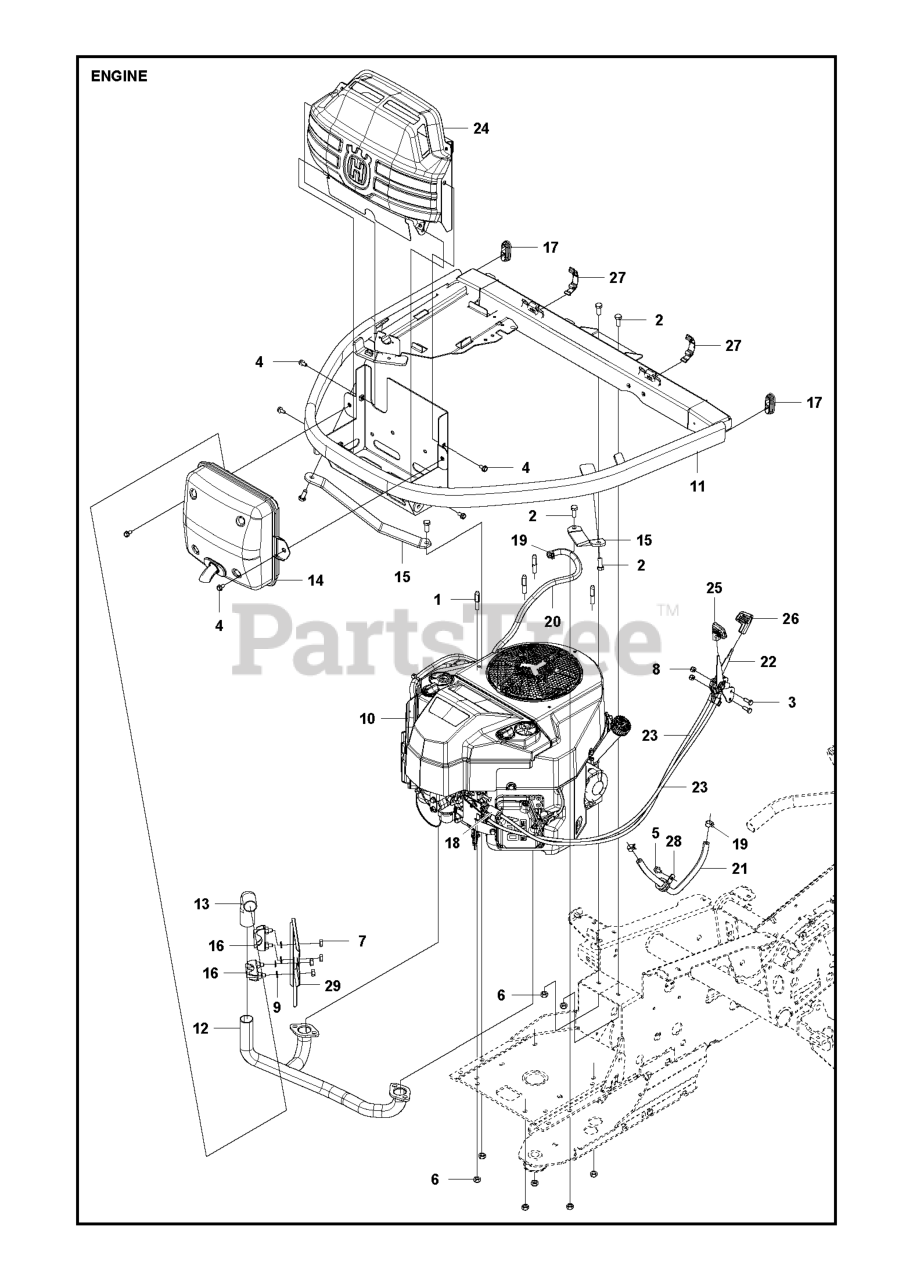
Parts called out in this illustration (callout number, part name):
1	STUD SCREW
3	BOLT FLANGE - M6X20
4	SCREW EHHFM
6	LOCKNUT M8
7	NUT
8	LOCKNUT M6
16	CLAMP ASSY EXHAUST
28	HOSE CLAMP
